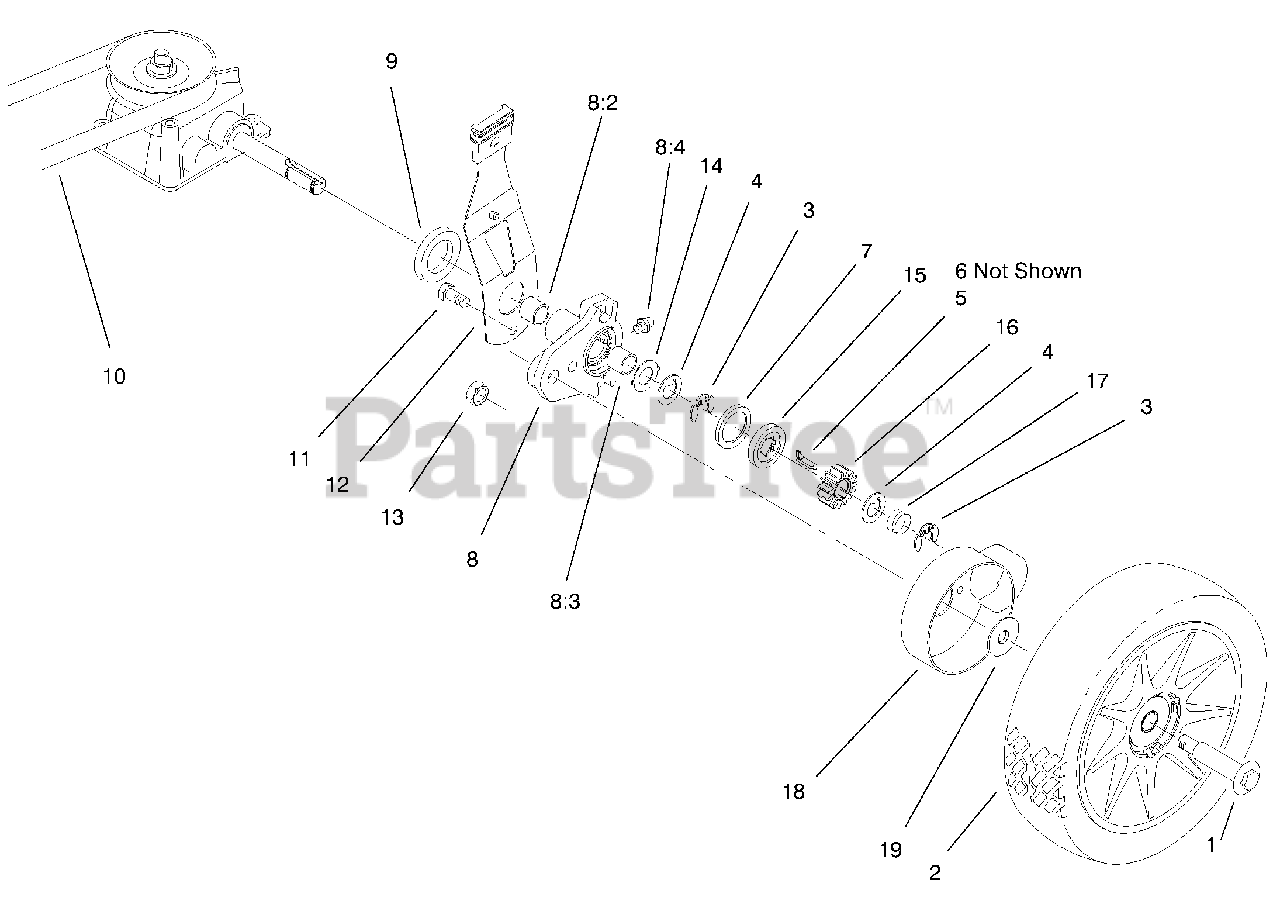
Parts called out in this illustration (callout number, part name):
1	Bolt-Shoulder
3	Ring-Retaining
4	Washer-Thrust
5	Key-Rocking LH
6	Key-Locking RH
7	Ring-Friction
8	ASM-Hgt Adj Arm
8:4	Fitting-Grease
9	Spacer-Axle Shaft
12	ASM-Spring Arm
13	Nut-Lock
14	Washer-Thrust
16	Gear-Pinion
17	Spring-Compression
18	Cover-Wheel
19	Washer-Stepped
